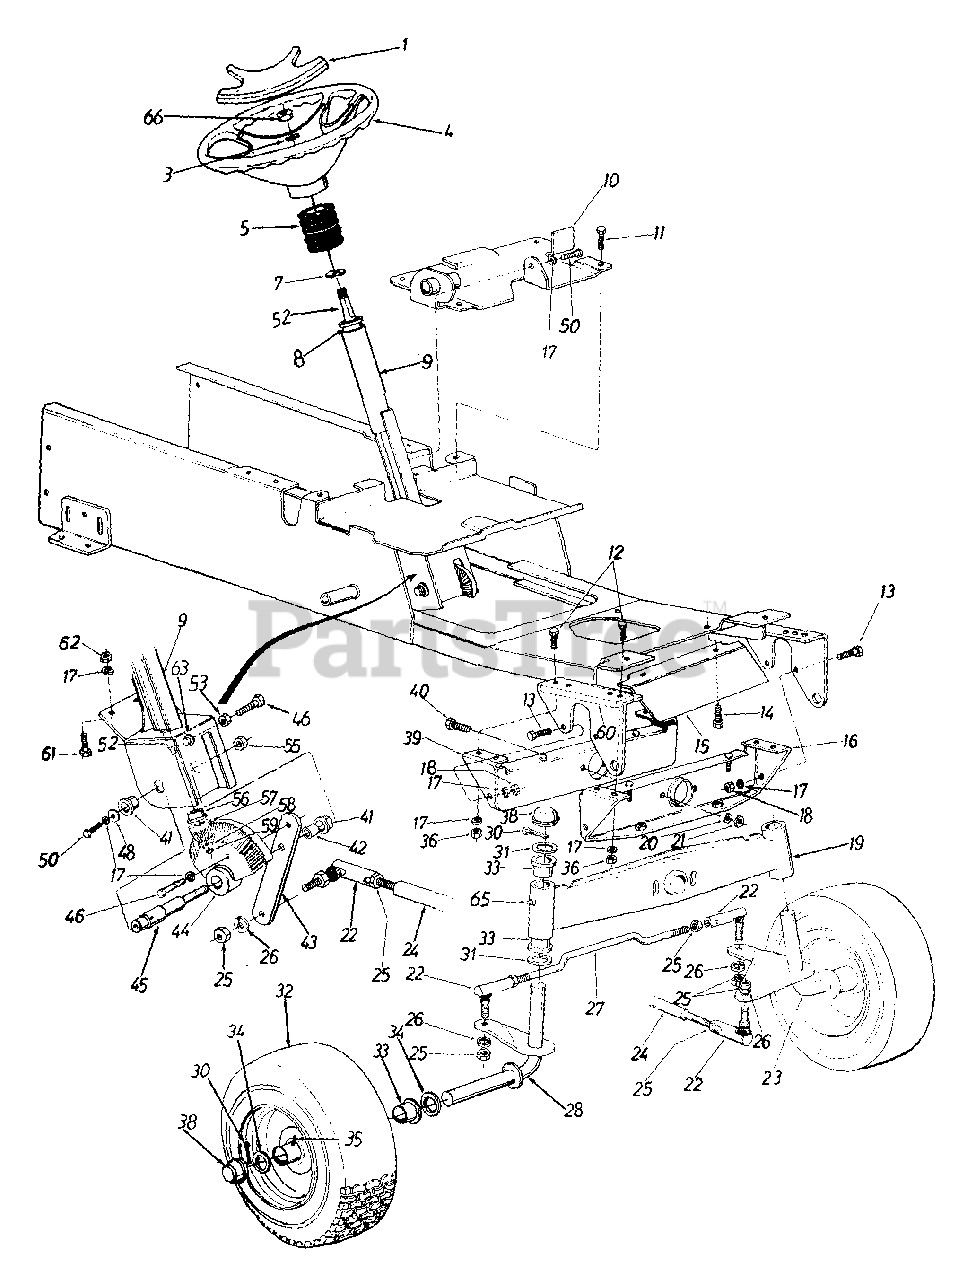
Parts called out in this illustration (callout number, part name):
1	Steering Wheel Insert
2	Hex L-Bolt 5/16-18 x 1" Lg.
3	Bell-Wash. 5/16" I.D.
4	Steering Wheel
5	Steering Bellow
7	Wave Wash. .660" I.D. x .88" 0 D.
8	Ball Brg. .63" I.D. x 1.38" O.D.
9	Steering Column Ass'y.
10	Dash Panel Base Plate Ass'y.
11	Hex Self-Tap Scr. 3/8-16 x .75" Lg.
12	Hex Bolt 3/8-16 x 1.50" Lg.
13	Hex Bolt 3/8-16 x 1.00" Lg.
14	Hex Wash. S.F. Tap Scr. 3/8-16 x 1.25" Lg.
18	Hex Nut 3/8-16 Thd.
19	Pivot Bar Ass'y.
20	Bell-Wash. 3/8" I.D.
21	Hex Cent. L-Nut 3/8-16 Thd.
22	Drag Link End
23	Axle Ass'y. - L.H.
24	Drag Link
25	Hex Nut 1/2-20 Thd.
26	L-Wash. 1/2" I.D.
27	Tie Rod
28	Axle Ass'y. - R.H.
30	Cotter Pin 3/16" Dia. x 1.50" Lg.
31	Fl-Wash. 1.00" I.D. x 1.62" O.D.
33	Flange Brg. 1" I.D.
34	Fl-Wash. 1" l.D. x 1.25" O.D.
35	Grease Fitting
36	Hex Nut 3/8-16 Thd.
38	Dust Cover
41	Flange Brg. w/Flats .753" I.D.
42	Steering Gear Shaft Spacer
43	Steering Arm
44	Bevel Gear
45	Steering Gear Shaft
46	Hex Bolt 3/8-16 x 1.50" Lg.
48	Fl-Wash. .406" I.D. x 1.25" O.D.
50	Hex Bolt 3/8-16 x .75" Lg."
52	Steering Shaft
53	Hex Jam Nut 3/8-16 Thd.
55	Hex Ins. L-Nut 1/2-20 Thd.
56	Hex Flange Brg. .630 I.D.
57	Pinion Gear
58	Fl-Wash. 3/8" Dia.
59	Hex Cent. L-Nut 5/16-24 Thd.
62	Hex Nut 3/8-24 Thd.
63	Cap
65	Grease Fitting
